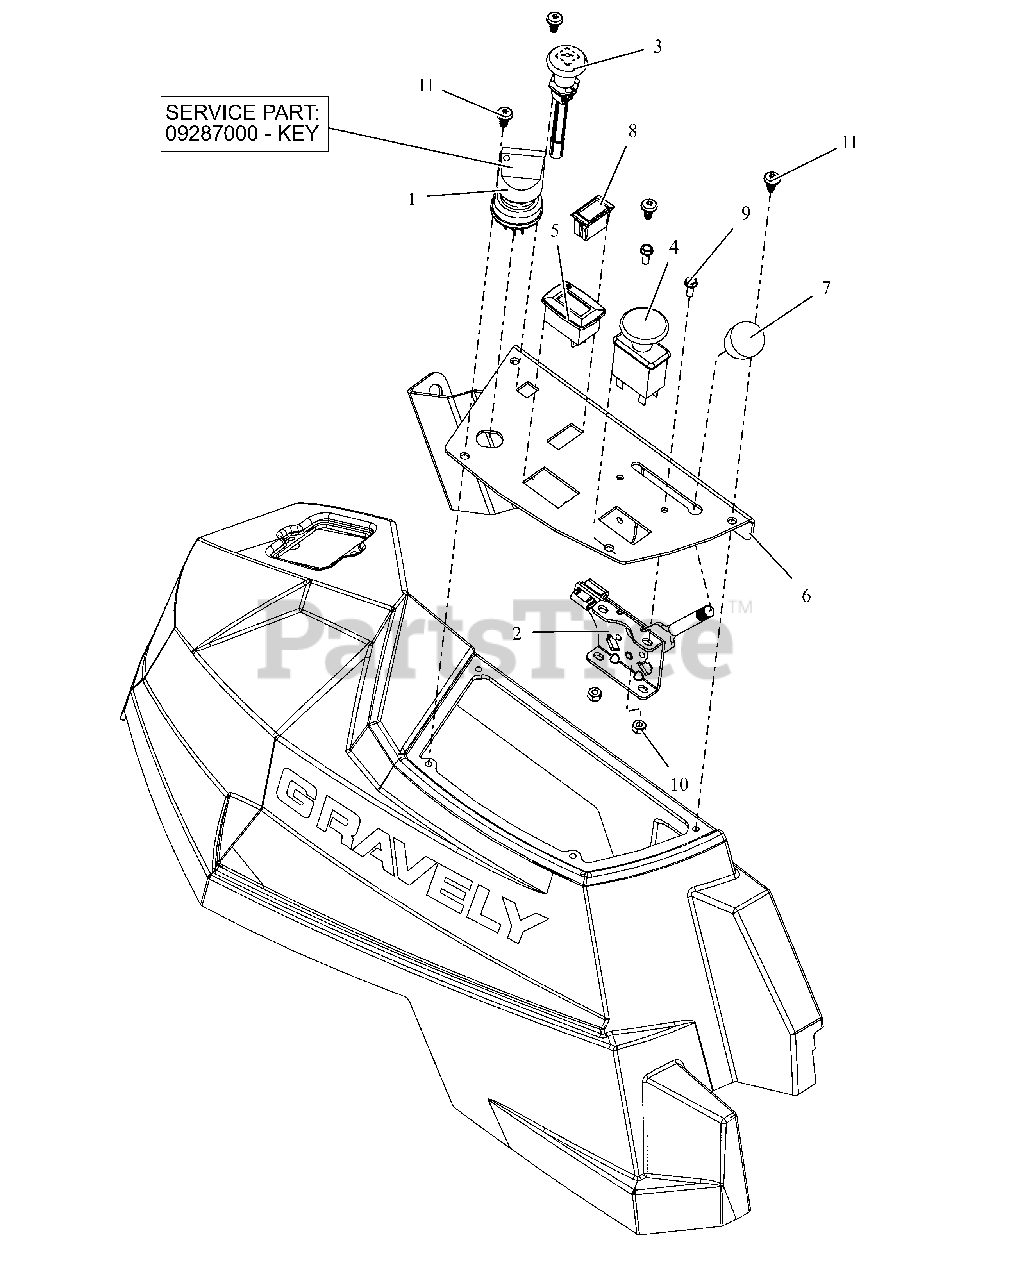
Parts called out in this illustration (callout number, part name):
1	SWITCH, IGNITION
1	KEY, W/ SHIELD
2	CABLE, PRO THROTTLE CONTROL
3	CABLE - CHOKE, SNAP-IN
4	SWITCH, CLUTCH
5	METER, HOUR W/MAINTENANCE
6	PANEL, HD CONTROL
7	KNOB-CONTROL-BLACK .38-16X.50
8	SWITCH,BLANK
9	BLT, HWH #10-24X.50 ZCC
10	NUT-LK-NYL #10-24 G2 ZCC
11	SCR-PAN .25-15X.50 6L H/LZB500
